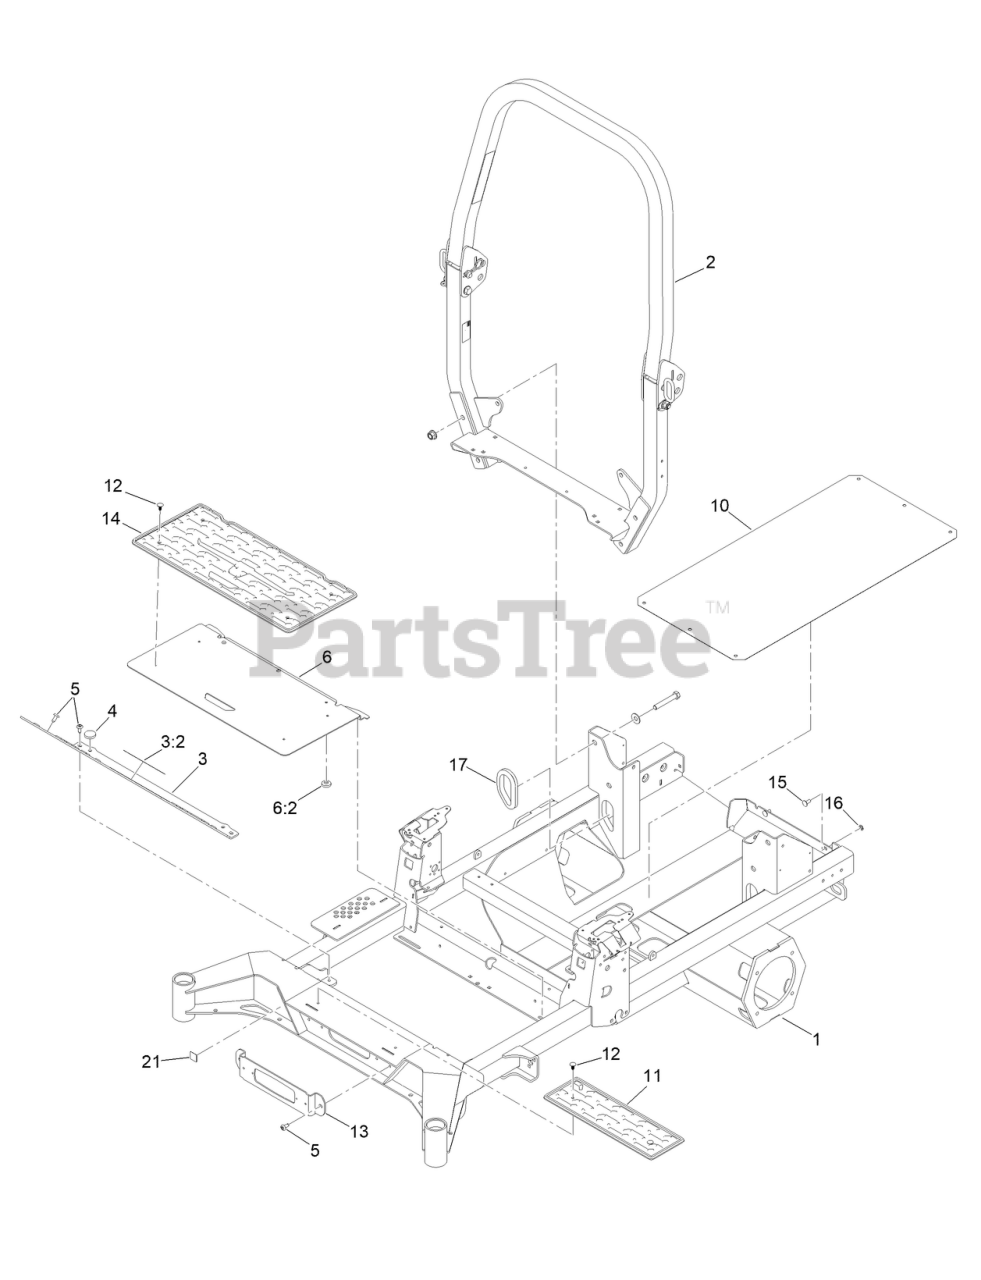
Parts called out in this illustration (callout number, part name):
2	ROPS ASM
3	TOEBOARD W/DECAL
3:2	DECAL-DANGER
4	BUMPER-PUSH-IN, RUBBER
6	ASM-FLOOR PAN
6:2	BUMPER-PUSH-IN, RUBBER
10	PLATE-SKID
12	PLUG-PLASTIC
13	BRACKET-LIGHT
14	FLOORMAT-FIXED SEAT
15	SCREW-CARR
16	NUT-PUSH
17	GROMMET-RUBBER
21	DECAL-LIGHT, WARNING
